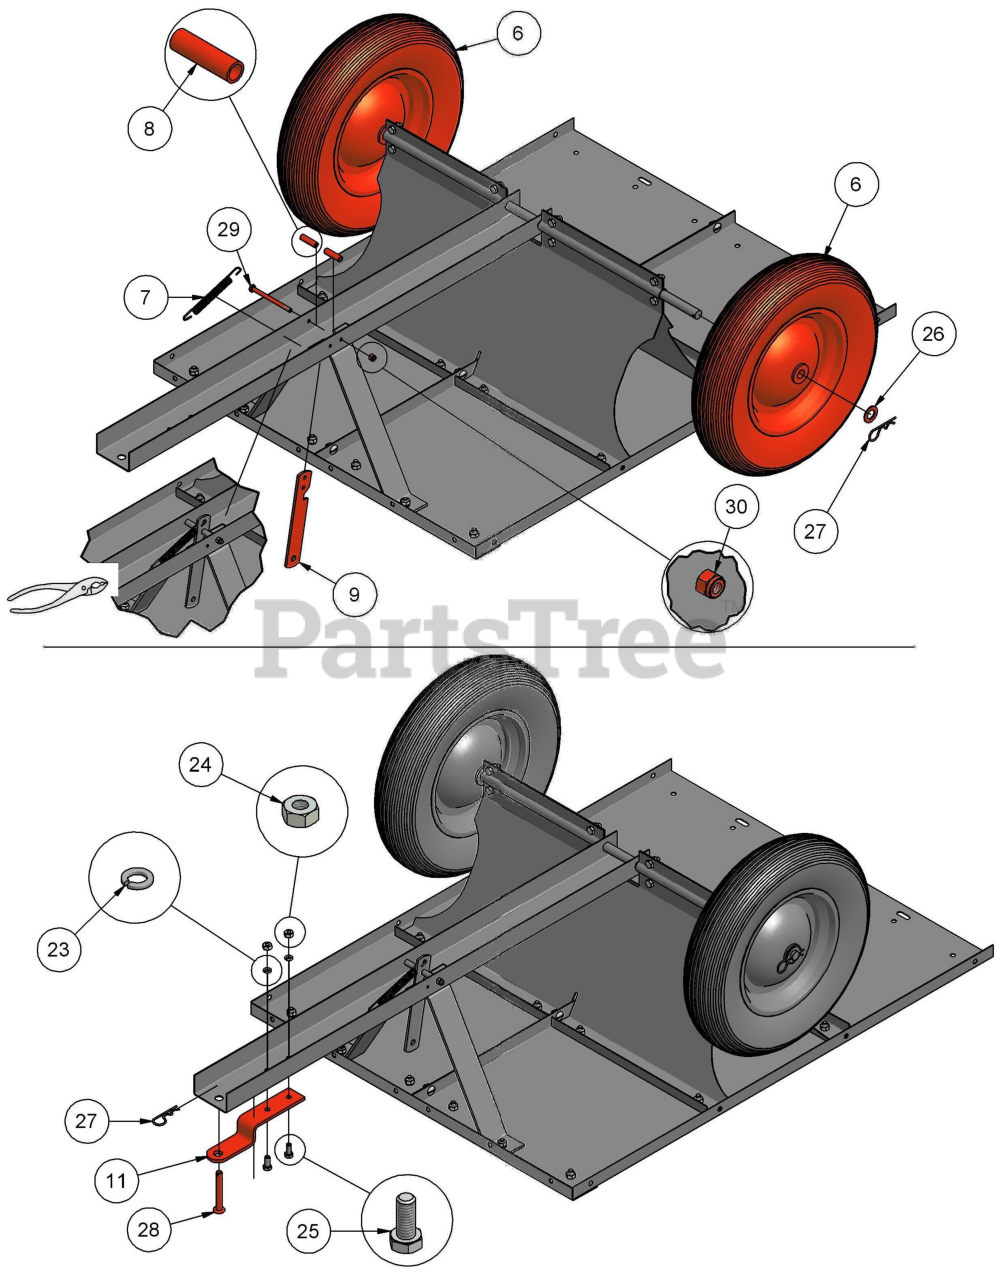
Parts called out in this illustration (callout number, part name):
6	WHEEL/TIRE ASSEMBLY
7	LATCH SPRING
8	LATCH SPACER
9	TONGUE LATCH
11	HITCH PIN BRACKET
23	8MM LOCK WASHER
24	8MM HEX NUT
25	M8 X 20 HEX BOLT
26	20MM FLAT WASHER
27	3MM HAIRPIN
28	HITCH PIN
29	M6 X 90 HEX BOLT
30	6MM NYLON NUT
